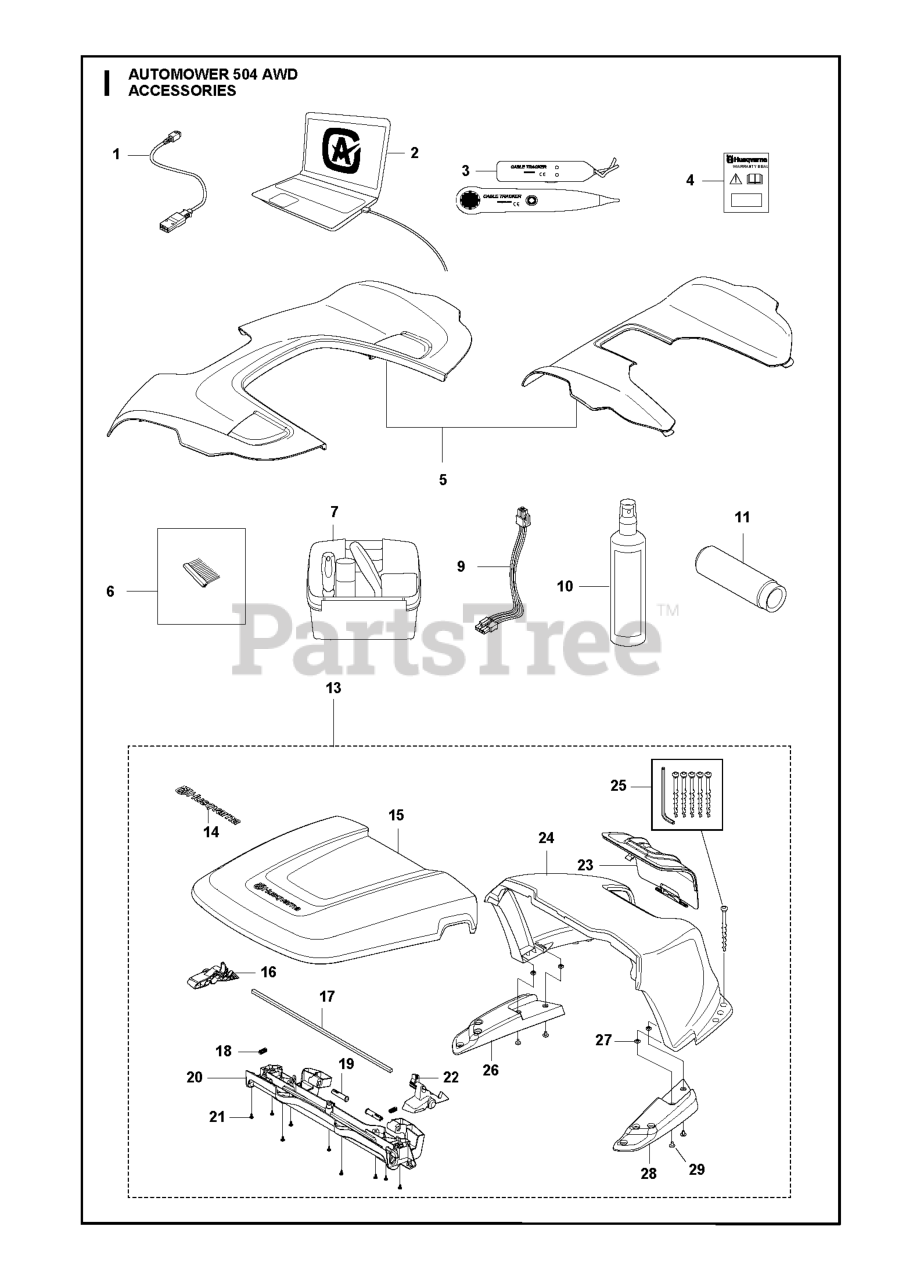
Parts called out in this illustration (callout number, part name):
1	CABLE ASSY QUICK CHARGER
3	TEST EQUIPMENT
4	LABEL WARRANTY SEAL DEALER
6	BRUSH WITH CARTON
7	CLEANING AND MAITENANCE KIT AM
9	WIRING ASSY BATTERY CABLE
10	AUTOMOWER ACCY
11	FLYWHEEL KNOCKER-FINE THREAD
14	DECAL
16	HANDLE RELEASE LEFT
17	ROD
18	SPRING SPRING CAP
19	HINGE PIN
20	BEAM
21	SCREW 14MM
22	HANDLE RELEASE RIGHT
23	HATCH
25	Screws
26	SUPPORT BASE LEFT
27	NUT
28	SUPPORT BASE RIGHT
29	SCREW IHPANM M6X25 4.6 ZP-BC
